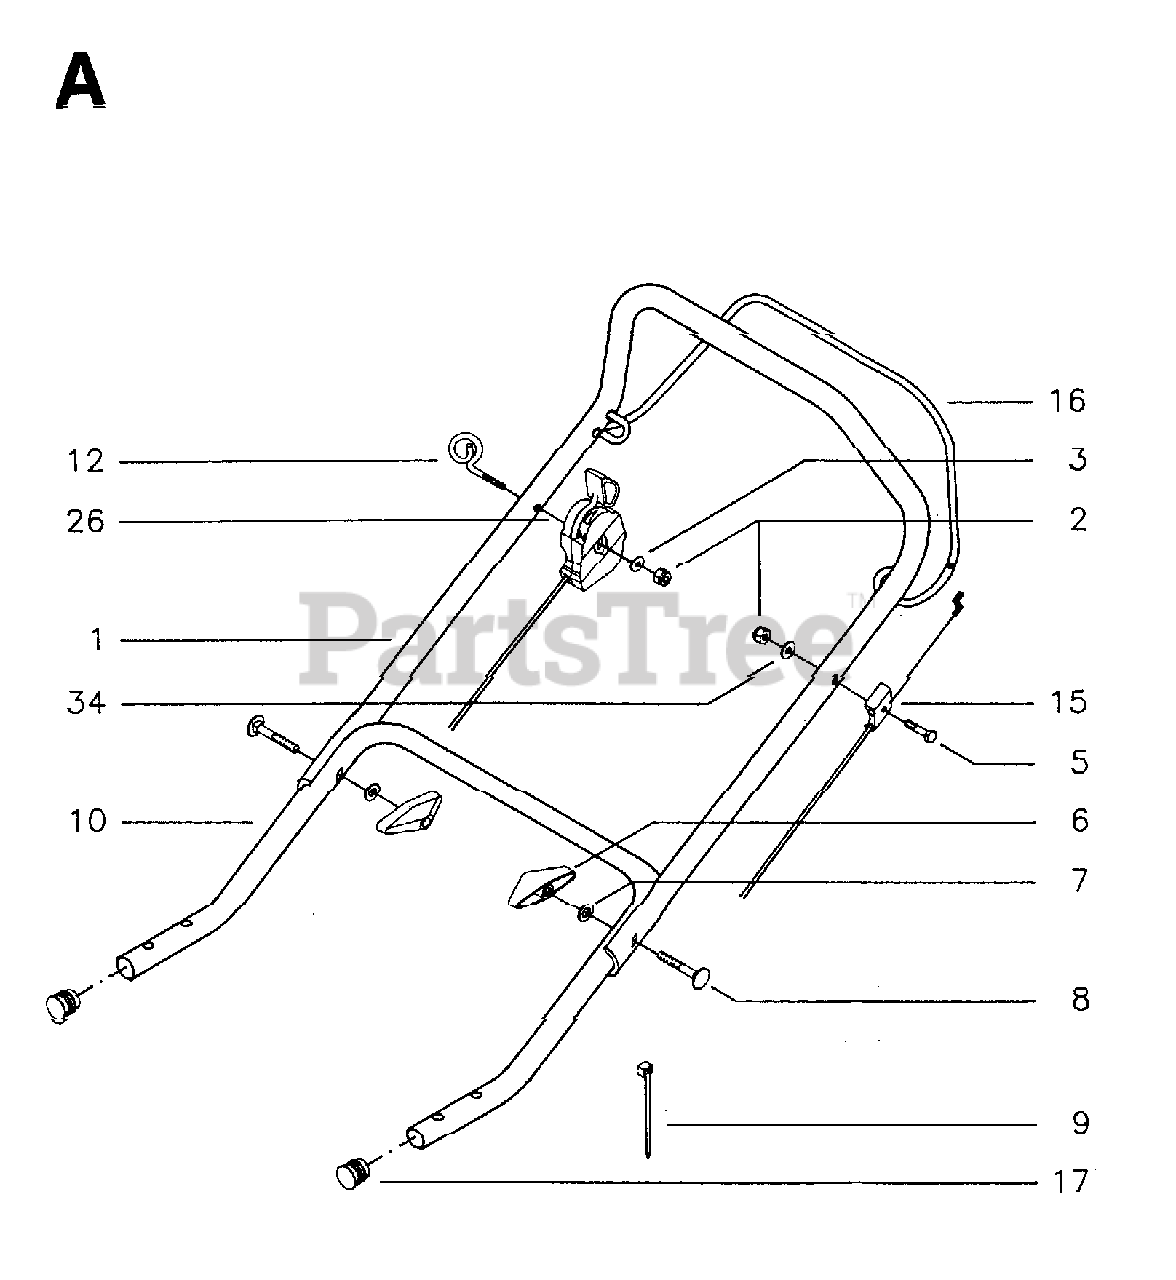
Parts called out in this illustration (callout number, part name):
2	LOCKNUT M6
5	BOLT FLANGE
26	THROTTLE TRIGGER
